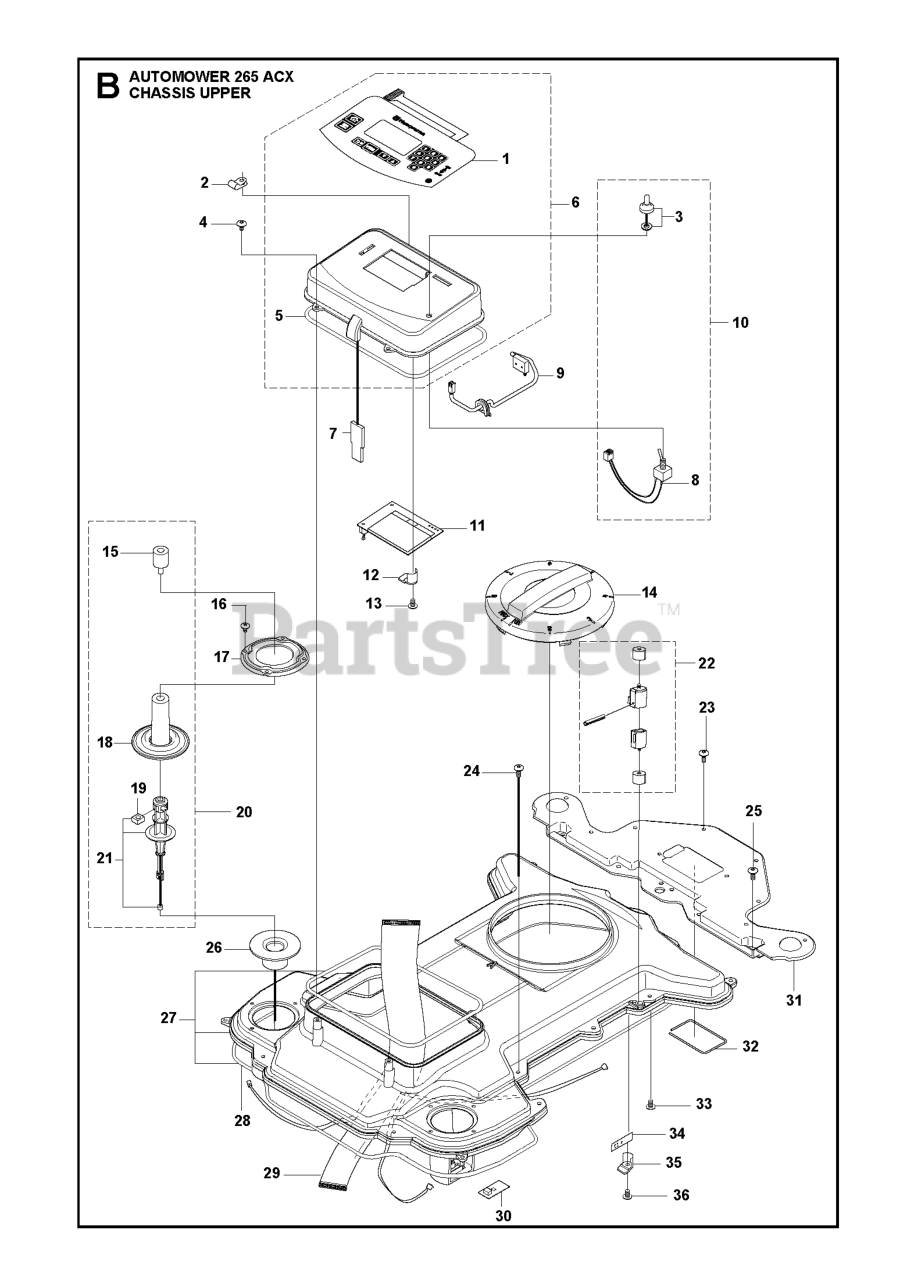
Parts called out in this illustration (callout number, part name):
2	CABLE CLAMP
3	RUBBER HOOD ON/OFF SWITCH
4	SCREW ITXPANT
5	SEALING STRIP
5	SEALING STRIP G2-2 DISPLAY CO
8	BRAKER
9	SWITCH KIT
13	SCREW 14MM
14	STEERING WHEEL
16	SCREW 14MM
17	RING FASTENER
18	RUBBER GAITERS
19	NUT
21	COLUMN ASSY
23	SCREW 14MM
24	SCREW ITXPANT
25	SCREW ITXPANT
26	MOVEMENT LIMITER
27	CHASSIS UPPER
28	SEALING STRIP
28	SEALING STRIP G2-2 CHASSIS
29	MAIN RIBBON HARNESS
30	PRINTED CIRCUIT ASSY
33	SCREW
34	PRINTED CIRCUIT ASSY
36	SCREW 14MM
